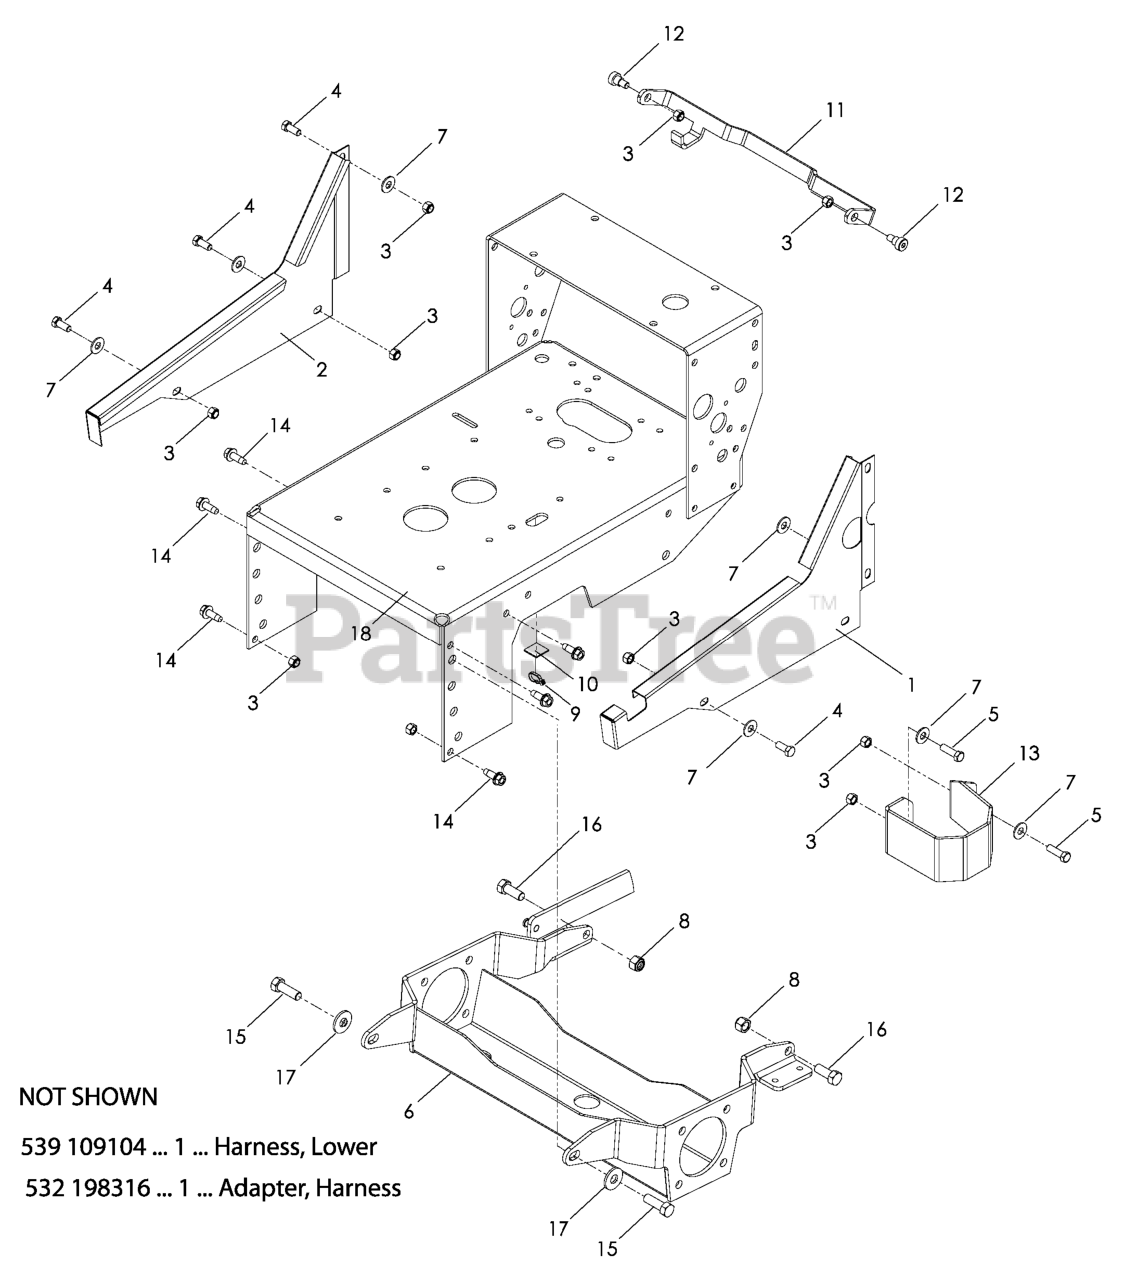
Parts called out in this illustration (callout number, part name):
1	PANEL - SIDE RH PAINTED
2	PANEL - SIDE LH PAINTED
3	NUT 3/8-16 NYLOC
4	HCS 3/8-16 X 7/8 GR 5 ZD
5	HCS 3/8C X 1 1/4 GR5
6	AXLE HYDRO
7	WASHER 3/8 FLAT
8	NUT 1/2-13 HEX NYLOC ZD
9	TIE, PLASTIC
10	MOUNTING BLOCK CABLE TIE
11	BAR THROW OUT, PAINTED
12	SB 3/8-16 X 3/8 SKT HD ZD
13	GUARD FILTER PAINTED
14	BOLT 3/8-16 X 1.0
15	HCS 1/2-13 X 1-1/2 GR 5 ZD
16	HCS 1/2-13 X 1-1/4
17	WASH USS FLAT 1/2
18	ENGINE CHASSIS W/DECAL
